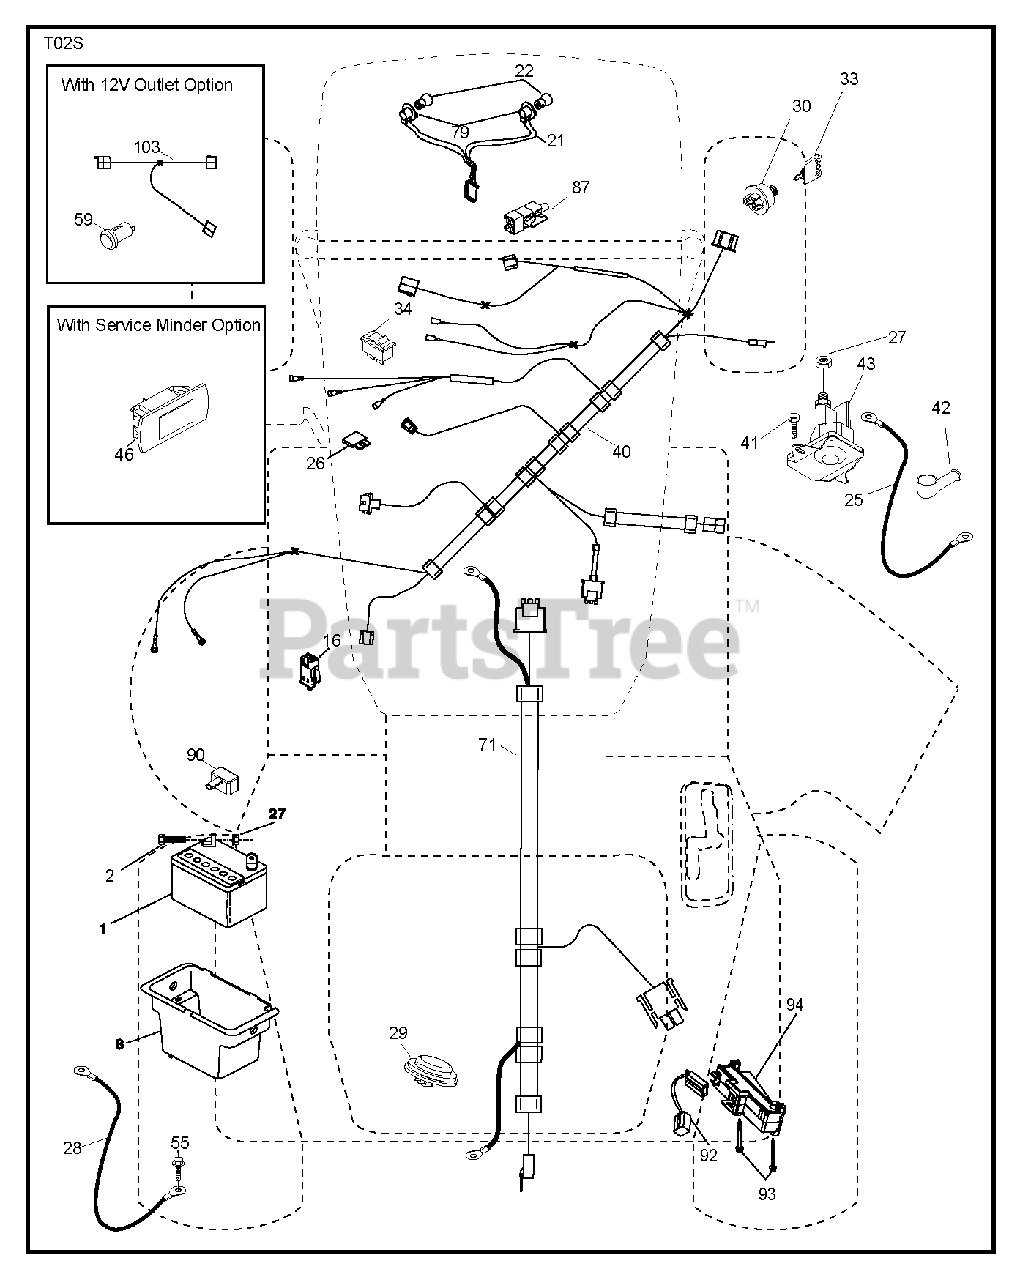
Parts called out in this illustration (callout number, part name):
1	REPL BY 532 12 38-99
2	BOLT.HEX.1/4.X.3/4.DICHROMATE
8	BOX.BATTERY.MNT.REAR.L
16	SWITCH INTERLOOK PUSH-IN
21	HARNESS ASSY LIGHT
22	LIGHTBULB
25	CABLE.STARTER.6GA.BL/RED.14.
26	FUSE 20AMP
27	NUT
28	CABLE.BLACK.18"REAR.BA
29	SWITCH.SEAT.DELTA.OPC.
30	SWITCH.IGN.DELTA.W.LGH.ROS
33	KEY.CHAIN.BLISTER.PACK.GEN.INT
34	SWITCH LT
40	HARNESS IGN. DASH
41	SCREW
42	TERMINAL COVER
43	SOLENOID.W/BRASS.PLUNGER
55	SCREW 5/16"
71	HARNESS.IGN.CHASS.TEX.REAR.BAT
79	BULB HOLDER ASM.
87	SWITCH.INTRLCK.CLUTCH.
90	COVER.TERMINAL.BATTERY
92	HARNESS.PIGTAIL.CONSLE
93	SCREW.PLASTITE
94	MODULE.REVERSE.ROS
